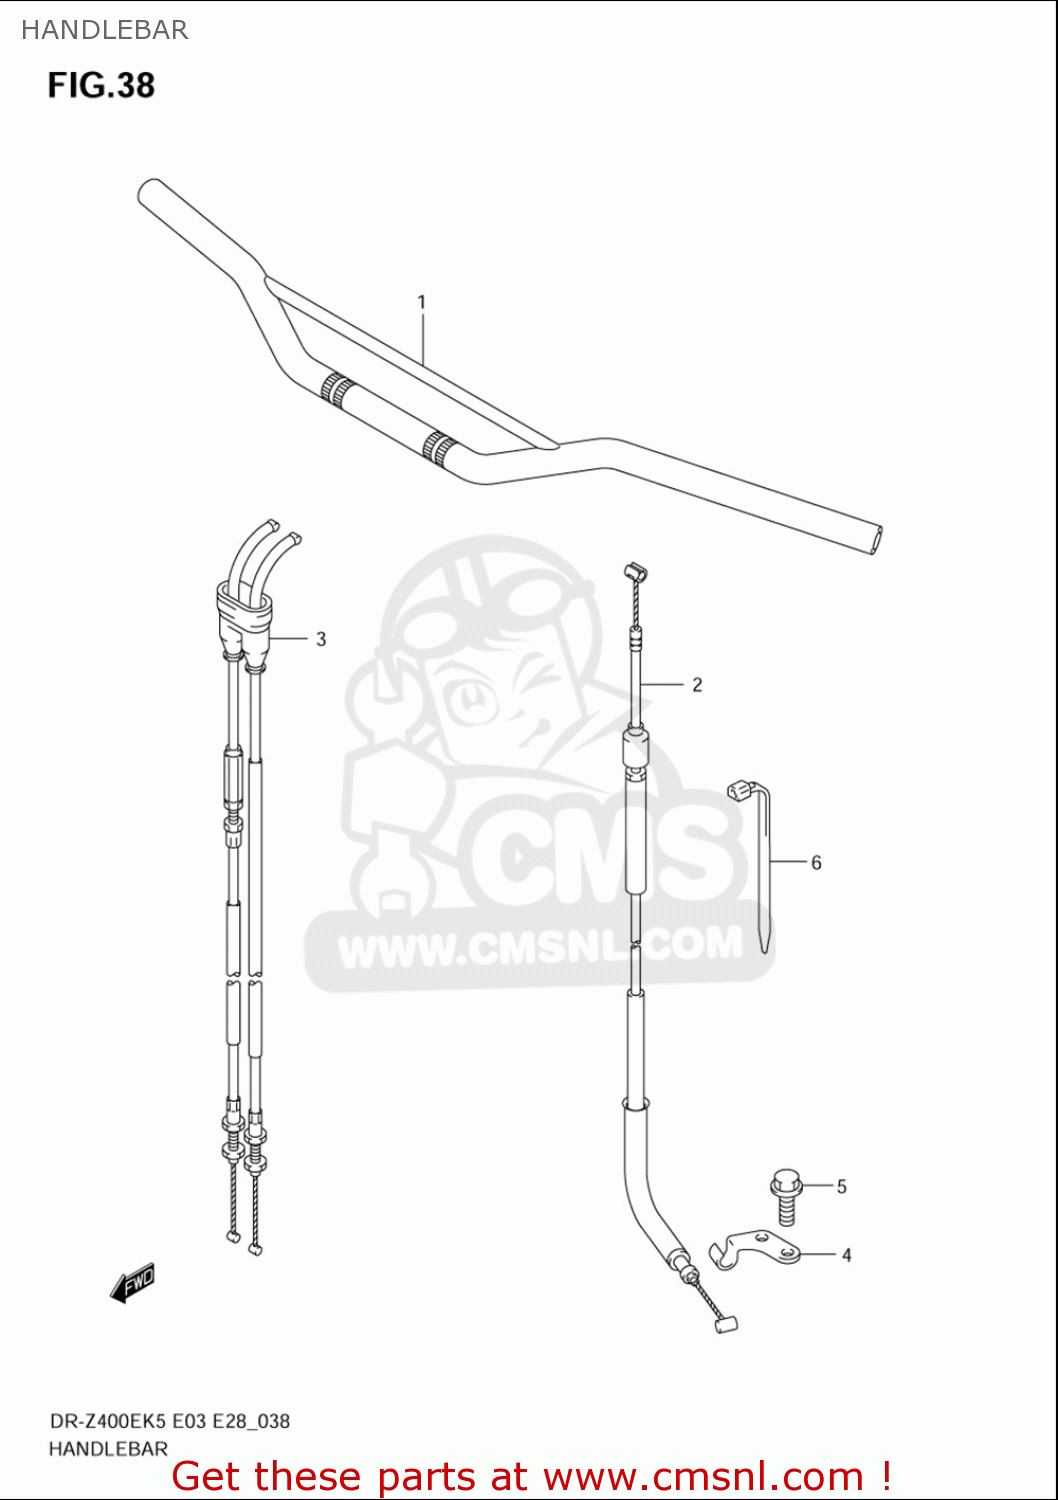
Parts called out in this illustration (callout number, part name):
1	HANDLEBAR(SILVER)
2	CABLE ASSY,CLUTCH
3	CABLE SET,THROTTLE
4	STOPPER,CLUTCH CABLE
5	BOLT
6	CLAMP(L:235)
